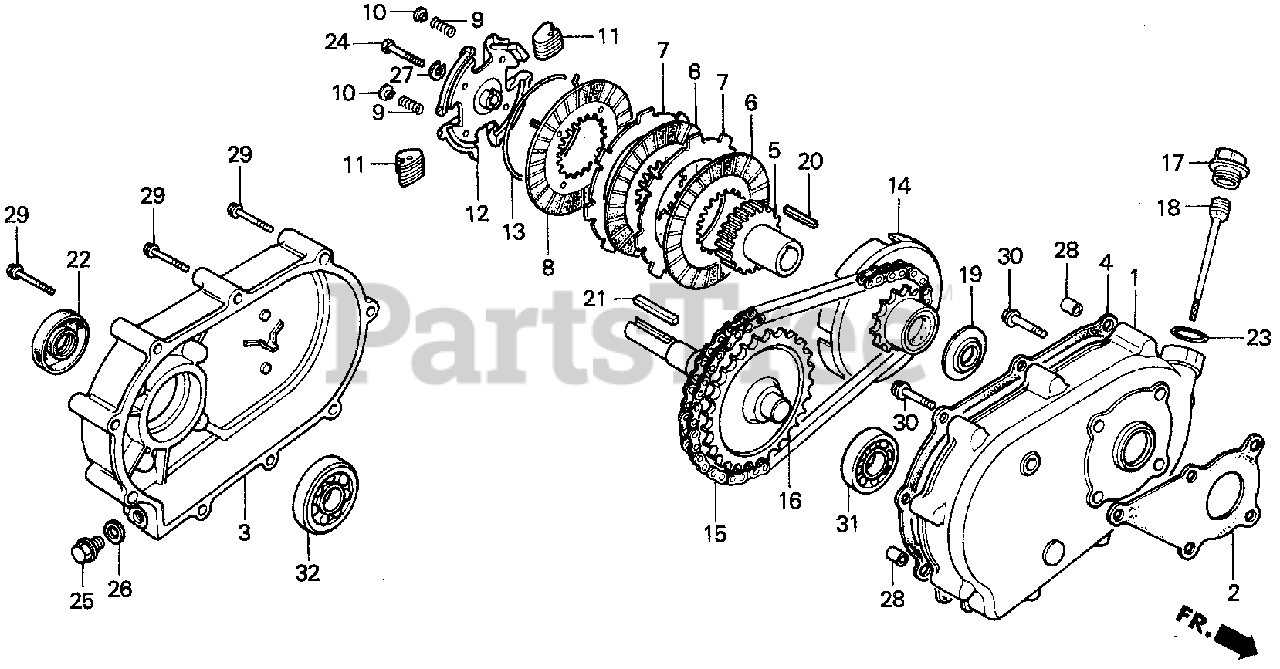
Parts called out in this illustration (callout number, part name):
1	CASE, REDUCTION
2	GASKET, REDUCTION CASE
3	COVER, REDUCTION
4	GASKET, REDUCTION COVER
5	CENTER, CLUTCH
6	DISK, CLUTCH FRICTION
7	PLATE, CLUTCH
8	PLATE, CLUTCH PRESSURE
9	SPRING, CLUTCH FREE
10	HOLDER, CLUTCH SPRING
11	WEIGHT, CLUTCH
12	HOLDER, CLUTCH WEIGHT
13	CENTER, CLUTCH WEIGHT
14	SPROCKET, DRIVE
15	CHAIN, DRIVE (RK428SH-36LE)
16	SHAFT, P.T.O. (28T)
17	CAP, REDUCTION OIL
18	DIPSTICK, OIL
19	WASHER, THRUST (20MM)
20	KEY (5MM)
21	KEY (7X7X33)
22	OIL SEAL (PJ30507)
23	O-RING (26X2.7)
24	BOLT, HEX. (8X35)
25	BOLT, DRAIN PLUG (12MM)
26	WASHER, DRAIN PLUG (12MM)
27	WASHER, SPRING (8MM)
28	PIN A, DOWEL (8X10)
29	BOLT, FLANGE (6X55)
30	BOLT, FLANGE (8X22)
31	BEARING, RADIAL BALL (6205)
32	BEARING, RADIAL BALL (6206)
